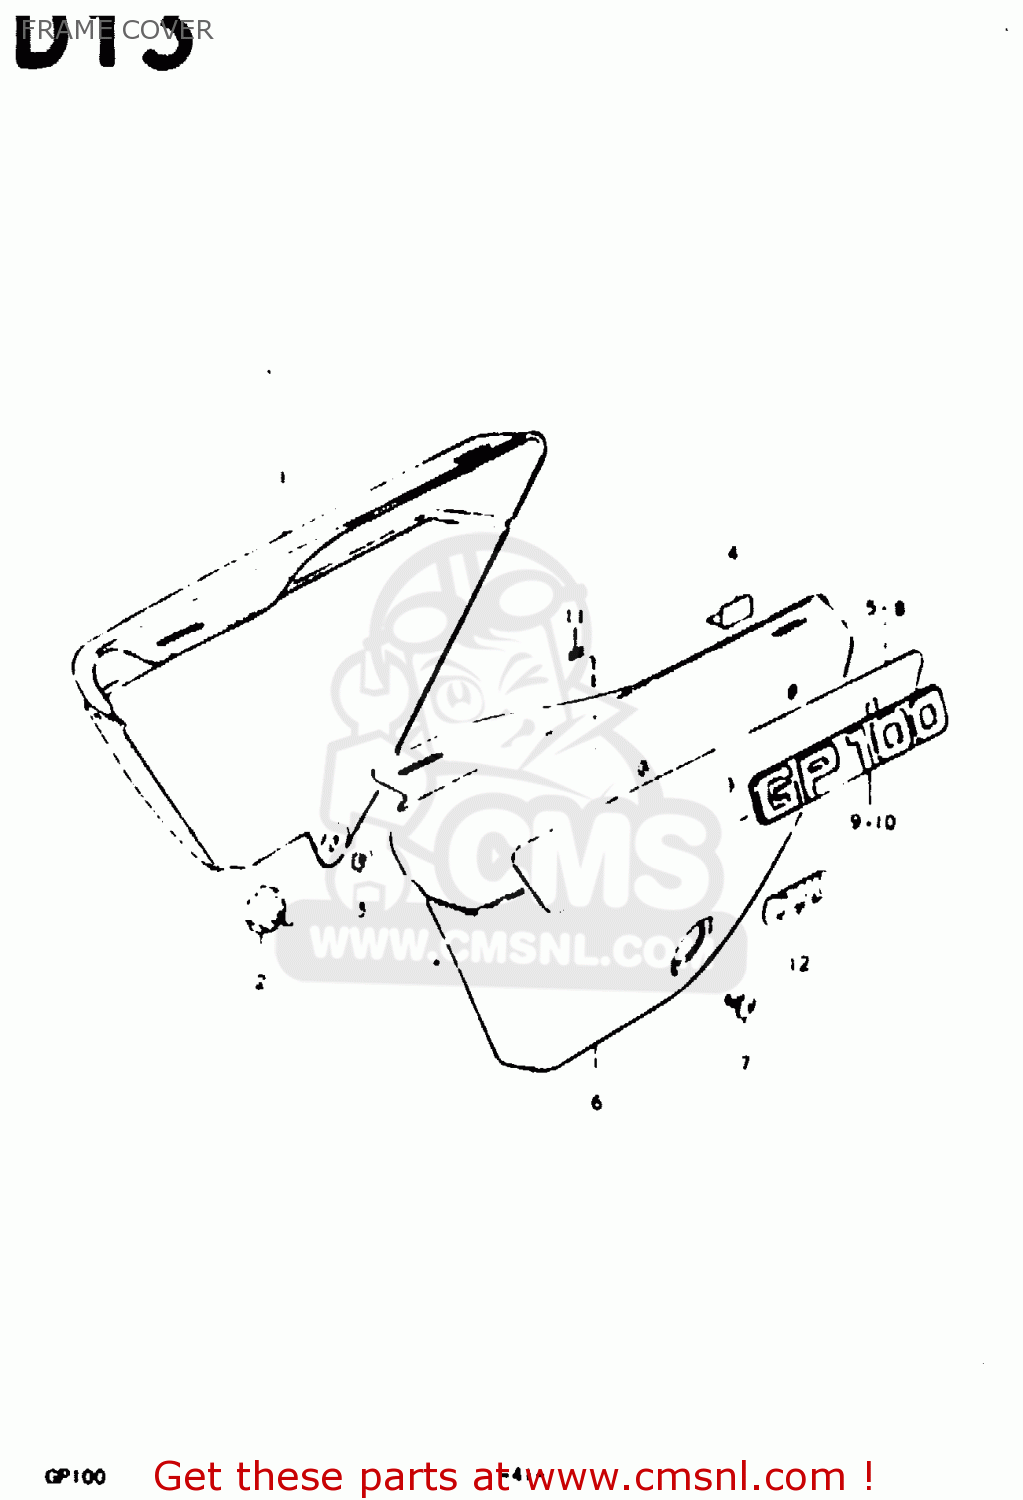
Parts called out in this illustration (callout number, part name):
1	COVER, FRAME RH
2	KNOB,FRAME COVER,R
3	NUT
4	CUSHION,FRAME COVER
5	TAPE, RH
6	COVER, FRAME LH
7	SCREW
8	TAPE, LH
9	EMBLEM
12	EMBLEM
